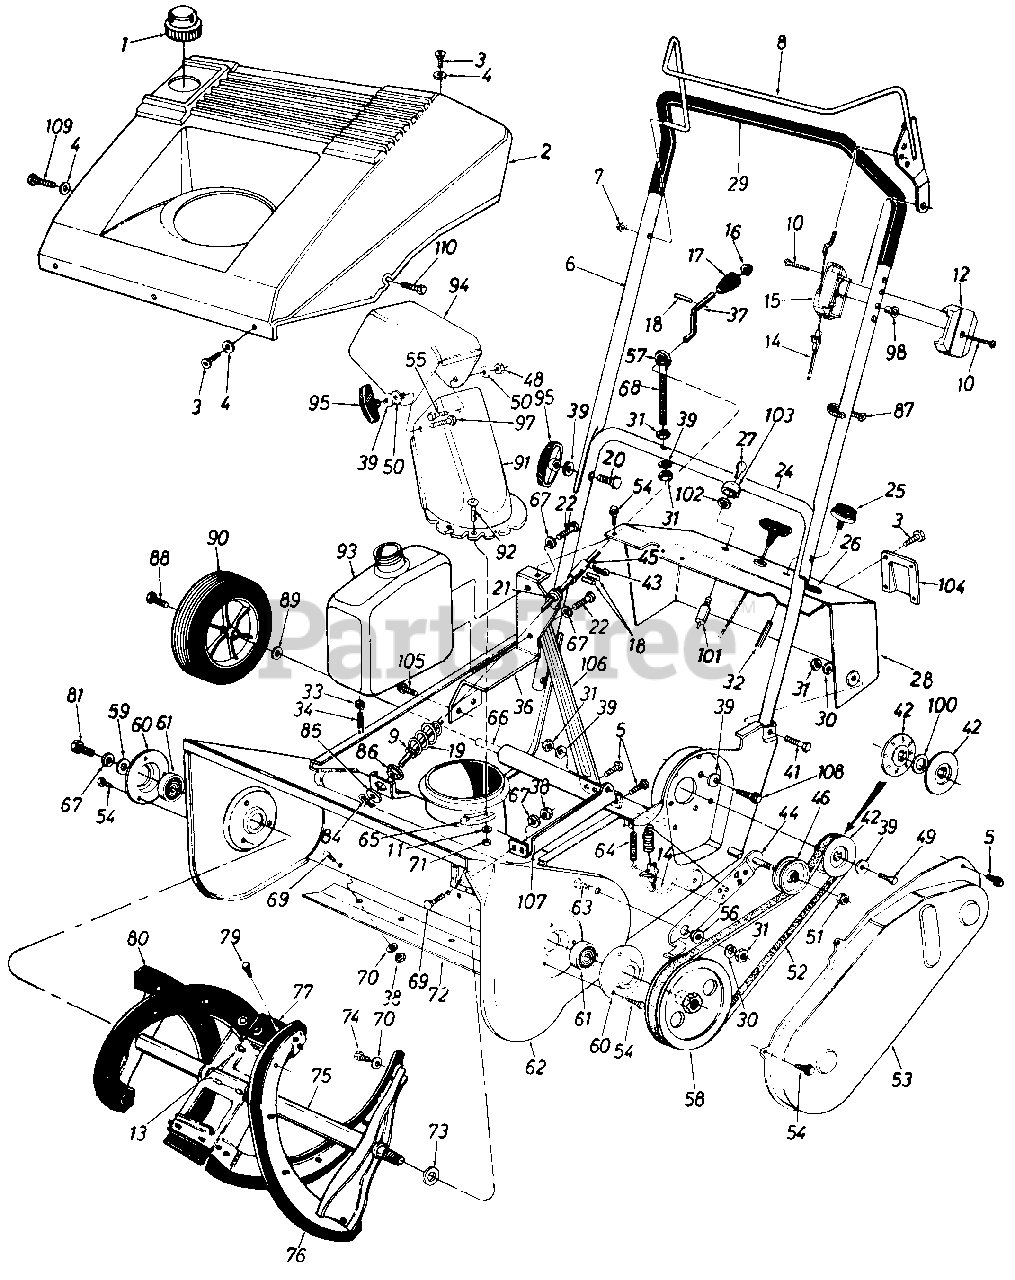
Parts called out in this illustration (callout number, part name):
1	Gas Tank Cap
2	Shroud
3	Hex B-Tap Scr. #10 x .5" Lg.
4	Fl-Wash. .203" I.D. x .41"
5	Hex L-Wash. Hd. AB-Tap 1/4 x .62" Lg.
8	Control Handle Ass'y.-L.H.
9	Fl-Wash. .385" I.D. x .62"
10	Truss Mach. Hi-B 0 Tap Scr. #12 x 1.5" Lg.
11	Fl-Wash. .281" I.D. x .5" O.D.
12	Control Panel Half
13	Pop Rivet 188" Dia.
14	Clutch Cable 35" Lg.
15	Control Panel Half
16	Push Cap 3/8" Rod
17	Knob-3/8" Dia. Hole
18	Roll Pin 1/8" Dia. x .63" Lg.
19	Lower Chute Crank Ass'y.
20	Curved Carriage Bolt 5/16-18 x 1.75" Lg.
21	Chute Crank Grommet
22	Hex Bolt 1/4-20 x .5" Lg.
24	Lower Handle
26	Plastic Plug
30	L-Wash. 5/16" I.D.
31	Hex Nut 5/16-18 Thd.
32	Primer Hose-9" Lg.
33	Hose Clamp-1/2" O.D.
34	Gas Line-16" Lg.
36	Gas Tank Support Brkt.
37	Upper Chute Crank
38	Hex Jam Nut 1/4-20 Thd.
39	Bell-Wash. .345" I.D. x .88"
41	Hex Bolt 5/16-18 x 1.5" Lg.
42	3/8" "V"-Pulley Half .625" I.D. x 6.0" O.D.
43	Hairpin Clip 3/8" Dia.
44	Idler Brake Brkt. Ass'y.
45	Spacer .38" I.D. x 1.12" Lg.
46	Fl-ldler w/Flanges 2.12" O.D.
48	Hex L-Nut 5/16-18 Thd.
49	Hex Bolt 5/16-24 x .75" Lg.
50	Fl-Wash. .344" I.D. x 1.25"
51	Hex Patch L-Nut 3/8-24 Thd.
52	V-Belt
54	Hex B-Tap Scr. 1/4" x .38" Lg.
55	Carriage Bolt 5/16-18 x .75"
56	Shld. Spacer .50" Dia. x .27"
57	Plastic Bushing .38" I.D.
58	1/2" "V"-Pulley l/2-2Q L.H. x 6"
59	Fl-Wash. 1/4" I.D. x .93" C.D.
60	Bearing Cup
61	Ball Brg. .669" I.D. x 1.574"
64	Extension Spring 1.12" Lg.
65	Chute Flange Keeper
66	Wheel Axle
67	L-Wash. 114" I.D.
68	Eyebolt
69	Carriage Bolt 1/4-20 x .50"*
70	Fl-Wash. .281" I.D. x .73"
71	Hex L-Nut 1/4-20 Thd.
72	Shave Plate
73	Fl-Wash. .510" I.D. x 1.0" O.D.
74	Hex Wash. B-Tap Scr. 1/4 X .62"
75	Auger Ass'y. 21"
76	Rubber Spiral-L.H.
77	Rubber Paddle
79	Hex Wash. B-Tap Scr. #10 x .62" Lg.
80	Rubber Spiral-R.H.
81	Hex Wash. TT-Tap Cl-Scr. 1/4-20 x .75" Lg.
84	Cotter Pin 3132" Dia. x .75"
85	Fl-Wash. .406" I.D. x 1.25"
86	Hex Bushing .385" I.D.
87	Cable Tie
88	Hex Tap Scr. 3/8-24 x .5"
89	Fl-Wash. .510" I.D. x .75"
90	7" Wheel & Tire Ass'y.
91	Lower Chute
92	Truss Mach. Scr. 1/4-20 x .75"
93	Fuel Tank-Two Qt.
94	Upper Chute
95	Knob Handle Ass'y.
97	Carriage Bolt 5/1 6-1 8 x 1"
98	Control Disc Pin
100	Fl-Wash. .635" I.D. x .93" O.D.
101	Key Switch
102	Ignition Switch Nut 5/8-32 Thd.
103	Ignition Switch Cap
104	Choke Cover
105	Hex Wash. Hd. Tap Scr. 1/4-.5" Lg.
108	Hex Bolt 5/16-18 x 518" Lg.
109	Pan Hd. Tap Scr. #10 x 1.25" Lg.
110	Hex Wash. Hd. Tap Scr. 1/4-20 x 1" Lg.
